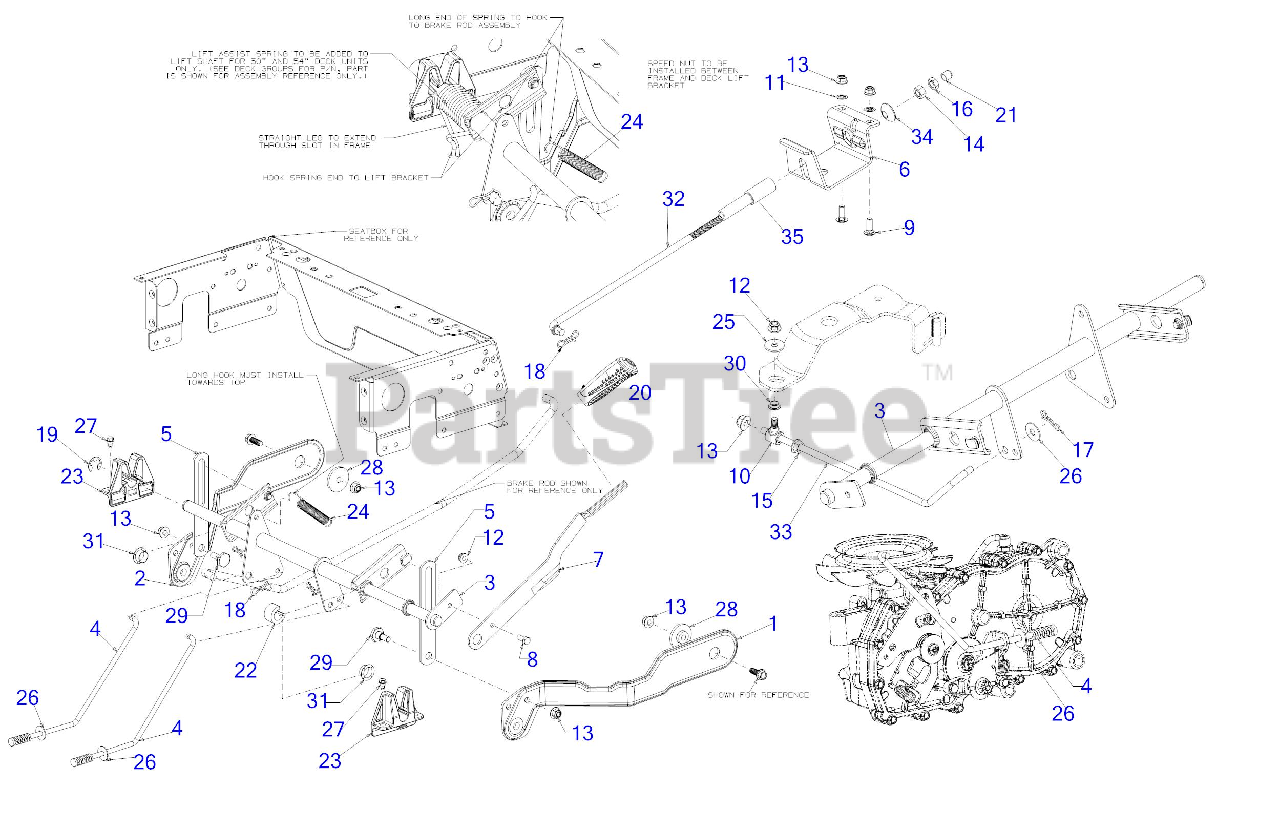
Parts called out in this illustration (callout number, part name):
1	DECK LIFT PLATE ASSEMBLY (RH)
2	DECK LIFT PLATE ASSEMBLY (LH)
3	DECK SHAFT ASSEMBLY
3	FLAT WASHER .75 x 1.13 x .10
4	BRAKE ROD ASSEMBLY W/SPRING
7	DECK LIFT HANDLE
8	SCREW 5/16-18 x .75 GR5
9	CARRIAGE BOLT 3/8-16 x 1.00 GR5
10	FERRULE 3/8 X 0.375
12	FLANGE LOCK NUT 5/16-18
14	HEX NUT NYLOK 1/2-13
15	HEX FLANGE NUT
16	HEX NUT
17	BOW TIE COTTER PIN 1/4-5/16
18	BOW TIE COTTER PIN
19	E-RING
21	LIFT ROD END CAP
22	SPACER: .76ID x .75
23	DECK LIFT BRACKET
24	EXTENSION SPRING .63 x 4.95
25	FLAT WASHER 1.0 OD:.331 ID
26	FLAT WASHER 344X1.00
27	SHOULDER SCREW 1/4-20X.50 19"PSH
28	SHOULDER SPACER -S
29	SHOULDER SCREW
30	FLANGE BEARING
31	FLANGE BEARING .75 x 1.125 x .375
32	DECK FRONT LIFT ROD
33	BRAKE DISENGAGEMENT ROD
34	DECK LIFT PIVOT CUP
35	SLEEVE .55 ID x 4.50 LG
